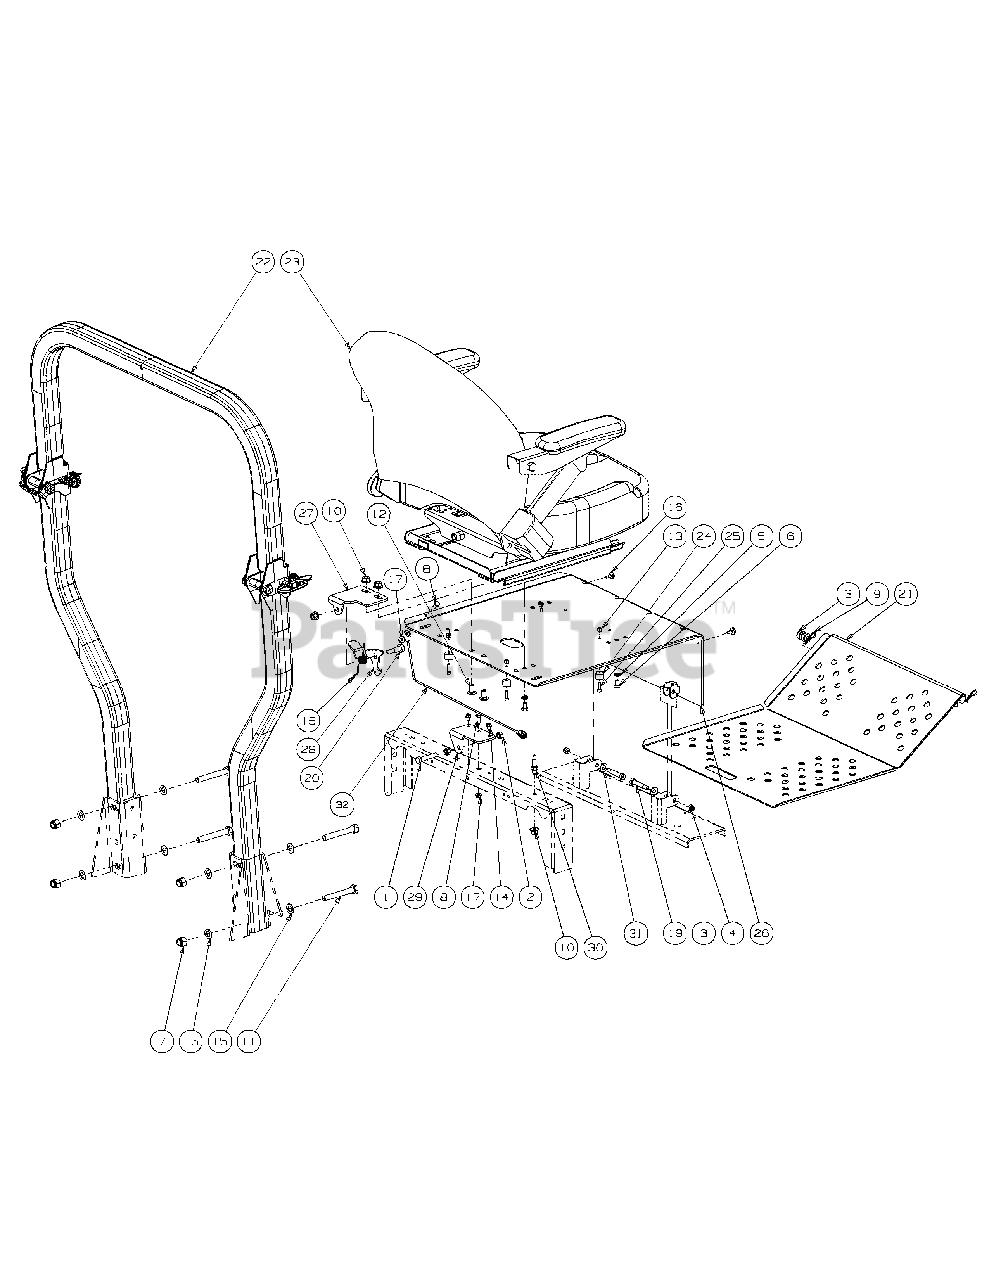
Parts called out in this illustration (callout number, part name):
1	Hex Cap Screw 3/8-16 x 2.00
2	Hex Nut, 3/8-16
4	Nylock Nut, 5/16-18
5	Lock Washer, 5/16
6	Hex Cap Screw, 5/16-18 x 1/2
7	Nut, 1/2-13, Nylon Insert
8	Screw, Hex, Cap, 1/4-20 x .75
9	Hair Pin, 3/8-1/2
10	Flange Lock, Hex Nut, 3/8-16
11	Hex Cap Screw, 1/2-13 x 3.50
12	Carriage Bolt, 3/8-16 x .75 Long
13	Nut, #10-24, Nylon Lock
14	Screw, TT, 1/4-20, 0.5, Hex Index Washer
15	Washer, .536 ID x .930 OD x .05
16	Rubber Bumper, .62 OD x .22 Thick
17	Lock Nut, 1/4-20
18	Deck Lift Spring, Left Hand
19	Shoulder Bolt, .375 x 1.50
20	Shoulder Bolt, 1/2 x 3/4, 3/8-16
21	Floor Panel Assembly
22	Foldable Rops Assembly
23	Seat w/ Seat Belt & Suspension
24	Rubber Stop with Washer
25	Standard Cap Screw, #10-24 x .75
26	Seat Plate Assembly
27	Seat Latch Bracket
28	Latch Lever Bracket
29	Latch Bracket
30	Adjustable Stud
31	Flat Washer, .406 ID, 1.0 OD .105
32	Cable Support
